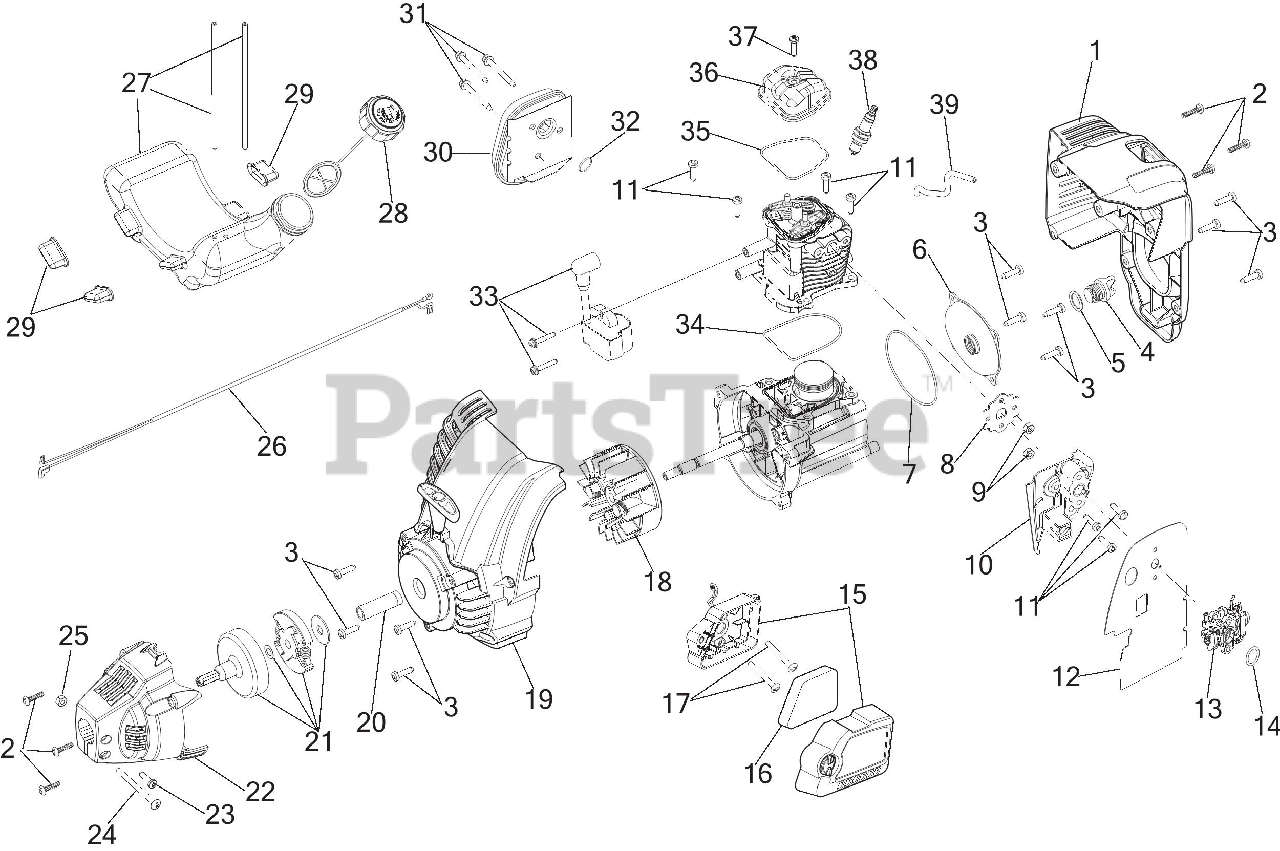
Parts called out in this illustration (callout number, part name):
1	ENGINE COVER ASSEMBLY RR
2	SCREW 8-16 x 3/4
4	OIL PLUG
5	RING, OIL PLUG (AC
6	CRANKCASE COVER
7	O-RING CRNKCSE CVR
8	GASKET/INSULATOR
9	NUT 10-32
10	INSULATOR
11	SCREW, M5 x 18.7MM
12	CARBURETOR GASKET
13	CARBURETOR
15	AIR CLNR COVER
16	AIR FILTER
17	SCREW 10-32X2.5
18	FLYWHEEL ASSEMBLY AC3.1
19	STARTER HOUSING ASSEMBLY
20	SPACER :2.165"
21	CLUTCH ASSEMBLY
22	CLUTCH COVER ASSEMBLY
23	SCREW 8-18X.375 T-20
24	SCREW
25	HEX NUT
26	WIRE LEAD
27	FUEL TANK ASSEMBLY
28	FUEL CAP ASSEMBLY 43MM-6 W/O HOLE
29	FUEL TANK PADS
30	MUFFLER ASSEMBLY
31	SCREW/MUFFLER
32	GASKET/MUFFLER
33	MODULE ASSEMBLY RFI
34	O-RING CYL AC5
35	O-RING
36	ROCKER COVER
37	SCR, VALVE COVER
38	SPARK PLUG 10MM:EM
39	HOSE, BREATHER
